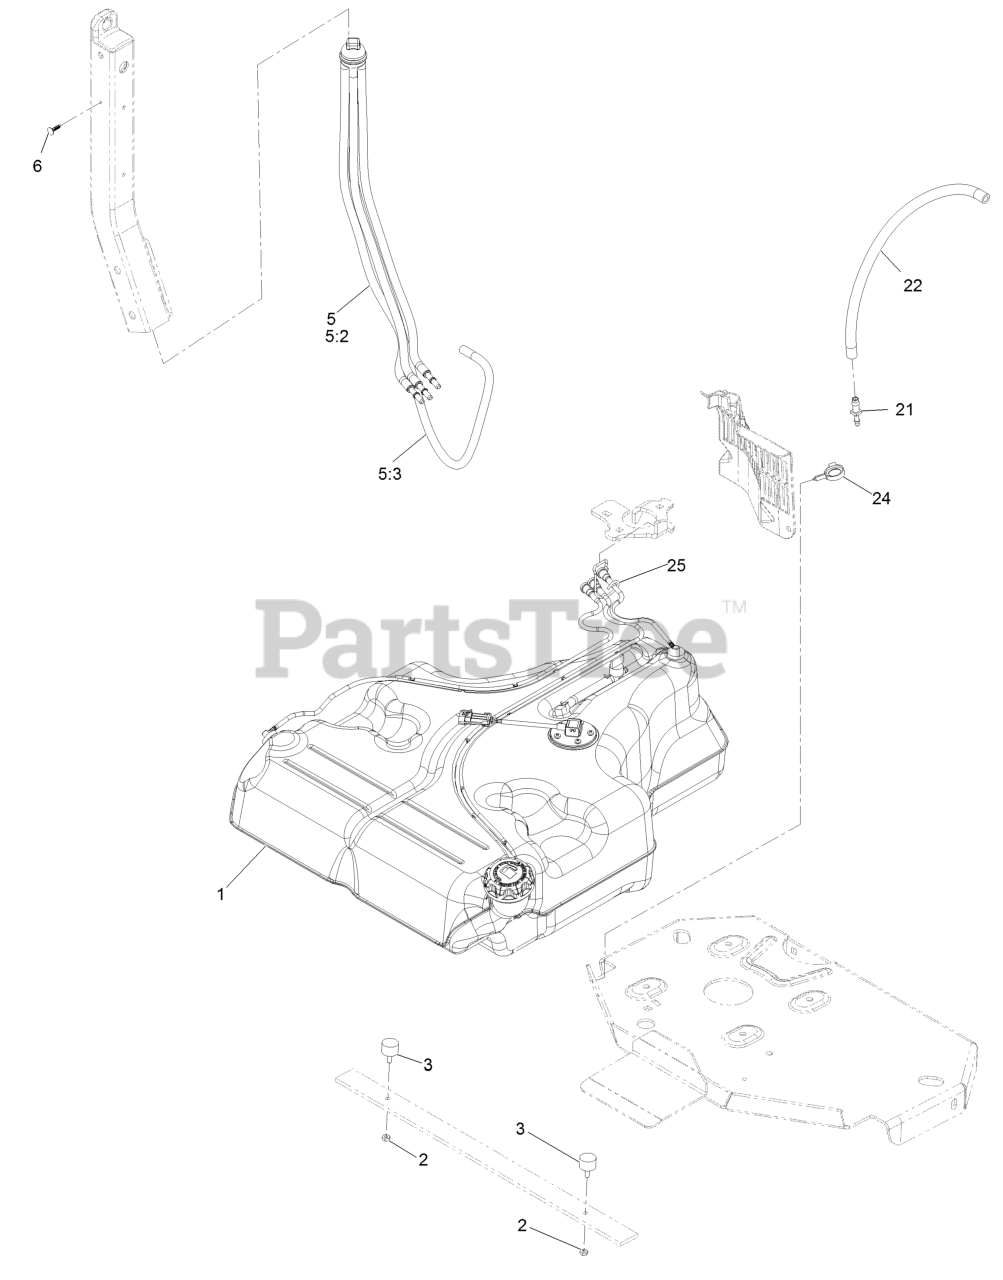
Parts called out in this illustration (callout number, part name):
1	FUEL TANK ASM
2	NUT-JAM
5	FUEL MANIFOLD VENT ASM
5:2	HOSE-FUEL
5:3	HOSE-FUEL
6	PLUG-PLASTIC
21	FITTING-STRAIGHT
22	HOSE-FUEL
24	CLAMP-HOSE
25	RETAINER-LINE, VAPOR
